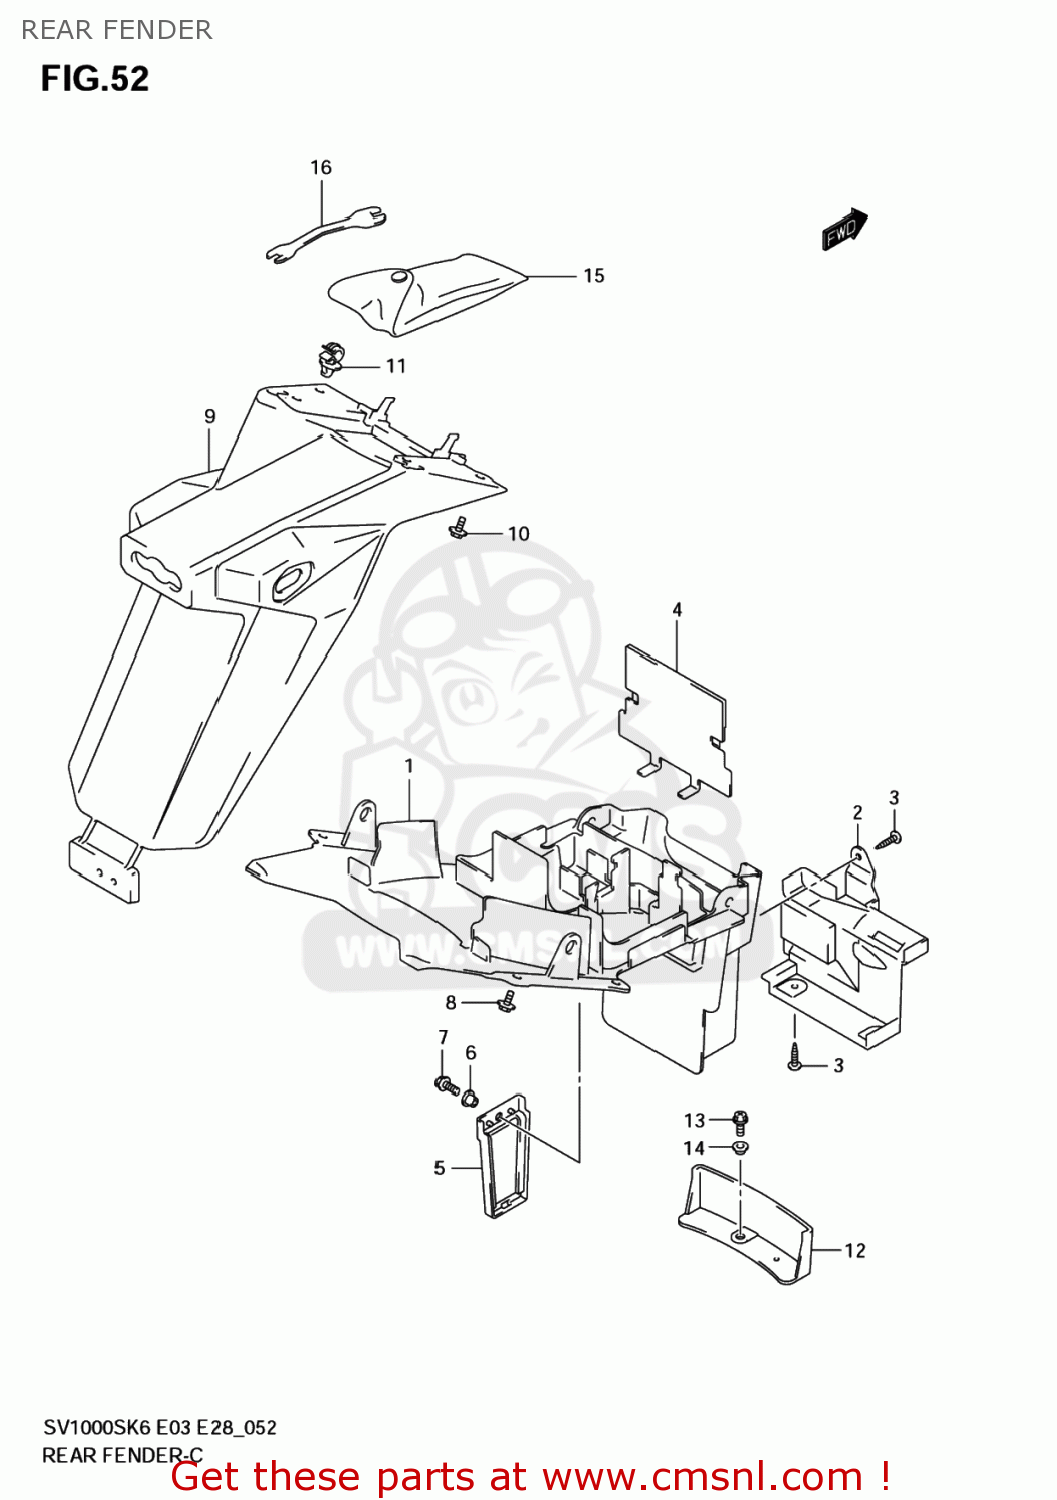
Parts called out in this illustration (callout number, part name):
1	FENDER,RR FR
2	COVER ASSY,RR FENDER FR
3	SCREW
4	COVER,RR FENDER UPR
5	LID,RR FENDER FR
6	GROMMET
7	PLUNGER
8	BOLT 6X14
9	FENDER,RR RR
10	BOLT 6X14
11	CLAMP
12	MUDGUARD,RR FENDER LWR
13	SCREW
14	WASHER
15	TOOL ASSY
16	SPANNER,OPEN
